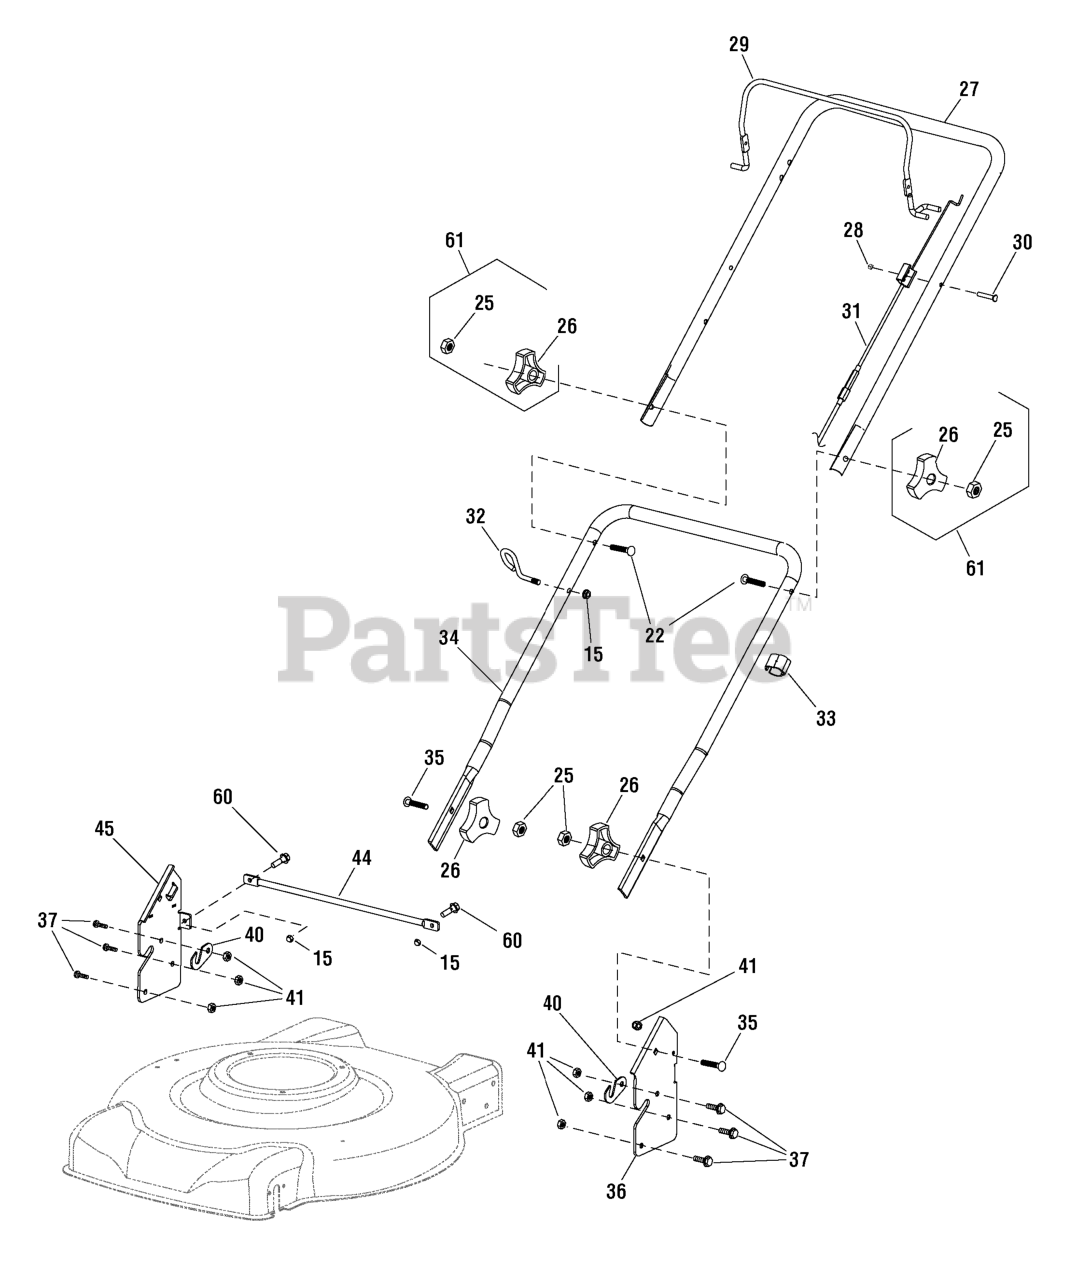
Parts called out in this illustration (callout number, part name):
15	NUT, M6
22	BOLT, Carriage, M8 x 45
25	NUT, M8
27	HANDLE, Upper
28	NUT, Acorn, M6
30	BOLT, M6 x 35
31	CABLE, Brake
32	ROPE GUIDE
33	CLIP, Cable
34	HANDLE, Lower
35	BOLT, M8 x 20
36	BRACKET, Handle, Left
37	BOLT, M8 x 20
41	NUT, M8
44	ROD, Support
45	BRACKET, Handle, Right
60	BOLT, M6 x 18
61	KIT, Hardware, Knob
